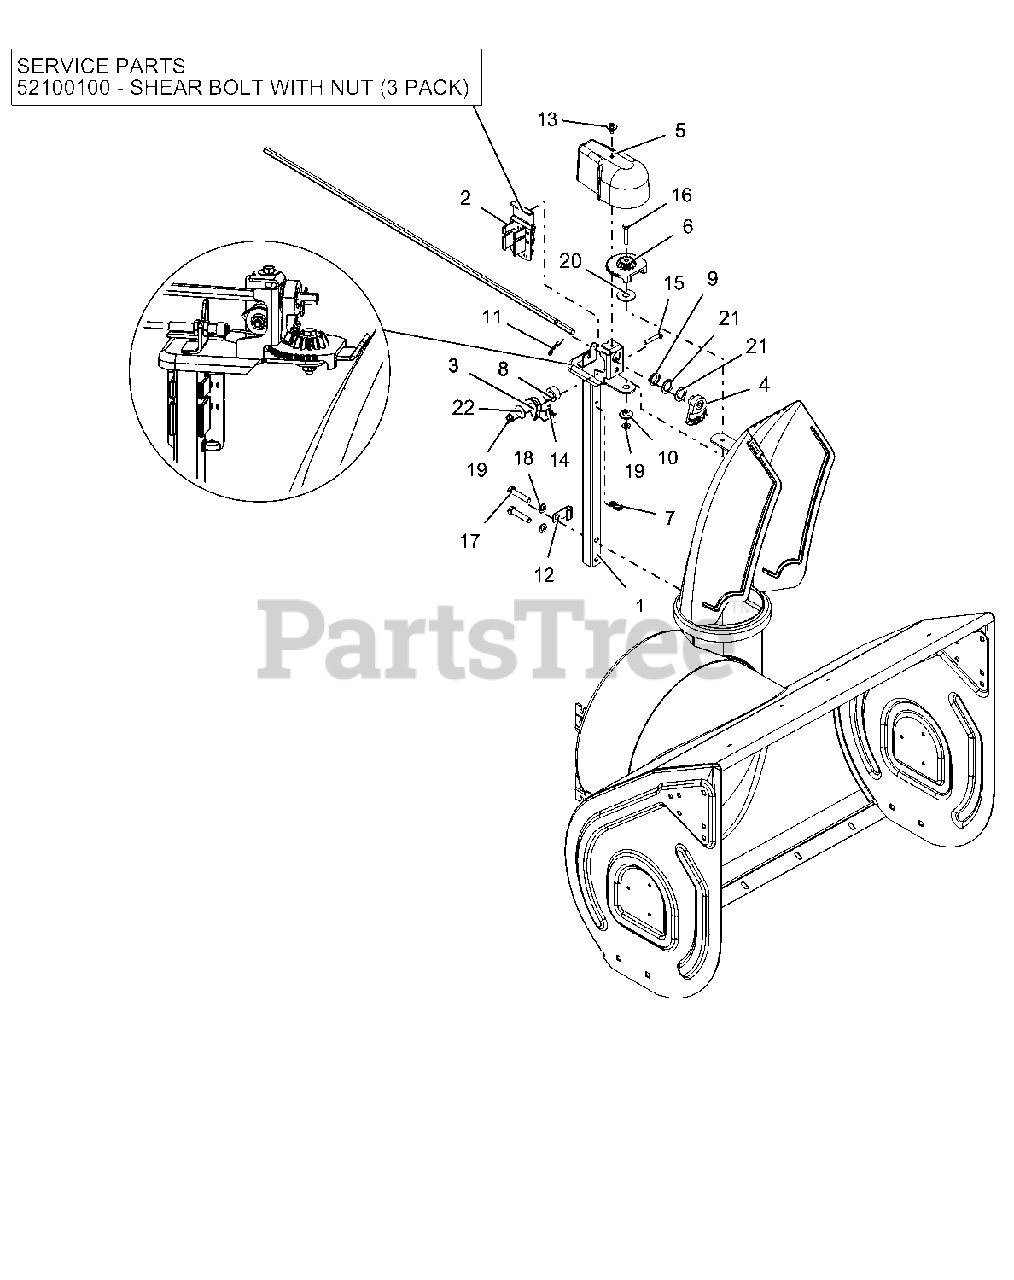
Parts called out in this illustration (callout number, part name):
1	PEDESTAL, CHUTE - QUICK STICK
2	HOLDER W LARGE SHEAR BOLT /NUT
3	ARM, LOCKING
4	GEAR, CHUTE-ACTUATION
5	COVER, CHUTE GEAR
6	GEAR, CHUTE
7	CLIP, CABLE GUIDE
8	BUSHING, LOCK ARM
9	BUSHING, POLYLINER-.75 SNAPIN
10	BSHG-FLG .265X.477X.375X1.00
11	PIN-HAIR INT .08X.18X1.18 YWZC
12	J-CLAMP
13	SCR-TAP .25-20X.50 LGHWH TR YZ
14	SG-TORS
15	@BLT-RDHDSQNK .25-20X1.50 G5YZ
16	@BLT-HEX .25-20X1.50 GR5 YWZC
17	@BLT-HEX .38-16X1.75 GR5 YWZC
18	@WSHR-LK .38X.094 REG YWZC
19	@NUT-LK-CTR-FLG .25-20 YWZC
20	WSHR-FLT-NYL .515X1.375X.093
21	WSHR-FL-STL.754X1.125X.062YWZC
22	WSHR-FL-STL .281X1.000X.063
23	SHEAR BOLT SERVICE ASSEMBLY
